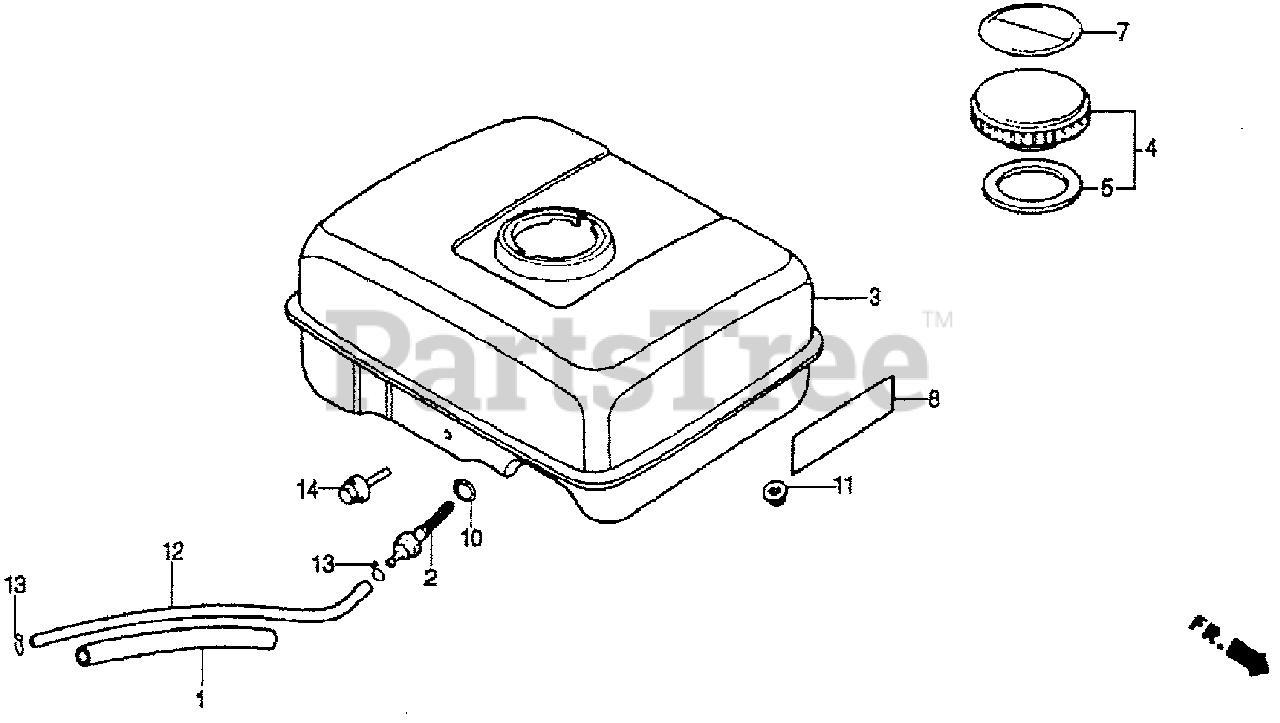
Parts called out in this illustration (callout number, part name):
1	RUBBER, SUPPORTER (107MM)
2	JOINT, FUEL TANK
3	TANK, FUEL *NH31* (MCKINLEY WHITE)
4	CAP, FUEL FILLER
5	GASKET, FUEL FILLER CAP
7	MARK, CAUTION (EXTERNAL)
8	LABEL, CAUTION
10	O-RING (13.5X1.5) (ARAI)
11	NUT, FLANGE (6MM)
12	BULK HOSE, FUEL (4.5X3000) (4.5X140)
13	CLIP, TUBE (B8)
14	BOLT, FLANGE (6X25)
